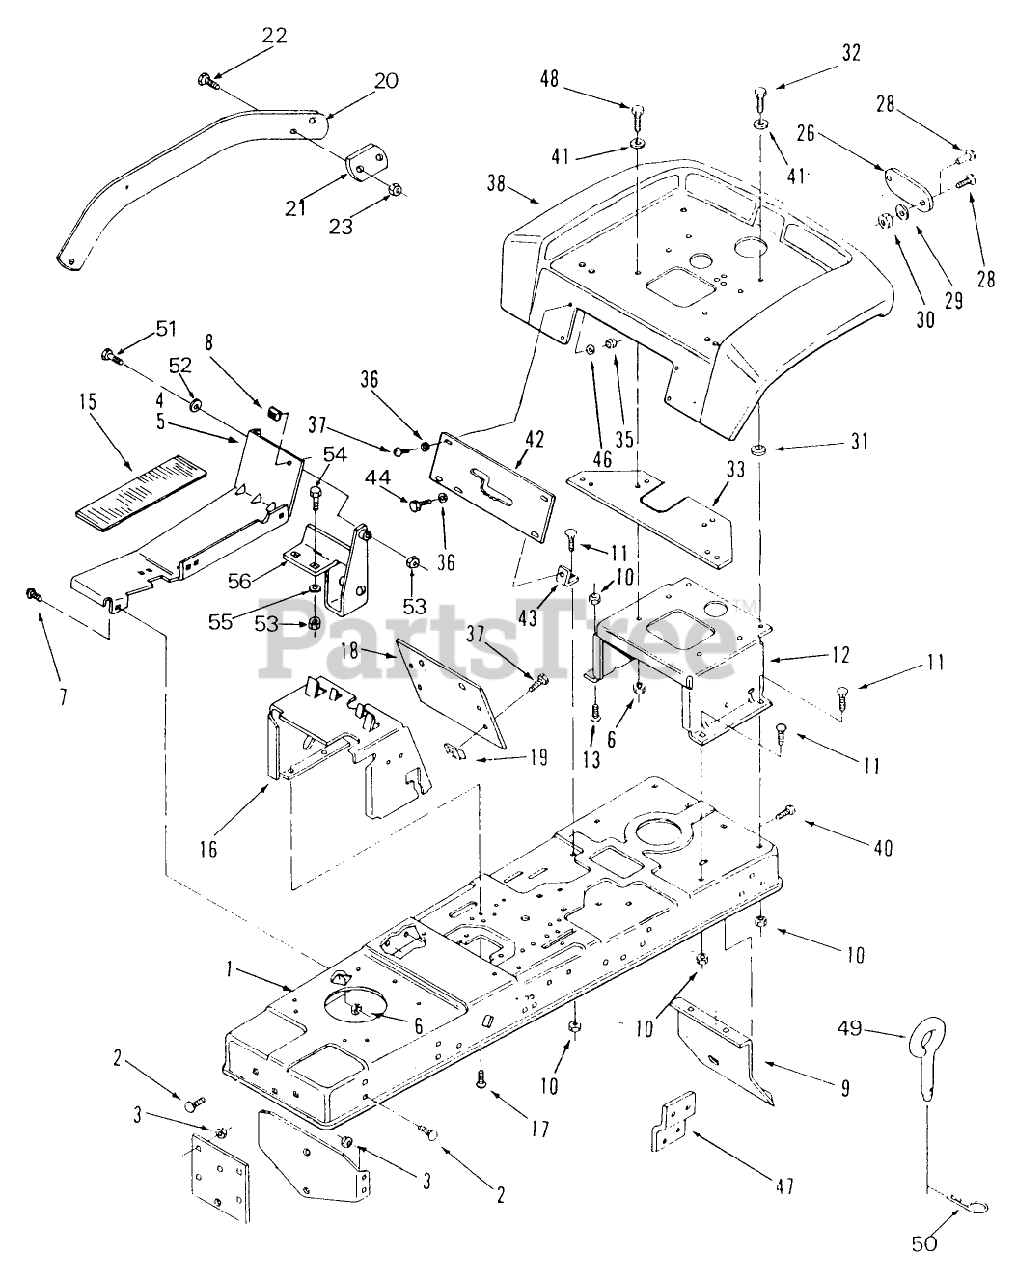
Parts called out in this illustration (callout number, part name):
8	BUMPER
17	SCREW
18	PLATE-HOODSTAND R *B
31	WASHER
41	WASHER 5/16 SAE
44	Bolt
49	PIN-TOOL
50	Hairpin Cotter
52	WASHER-SPECIAL
